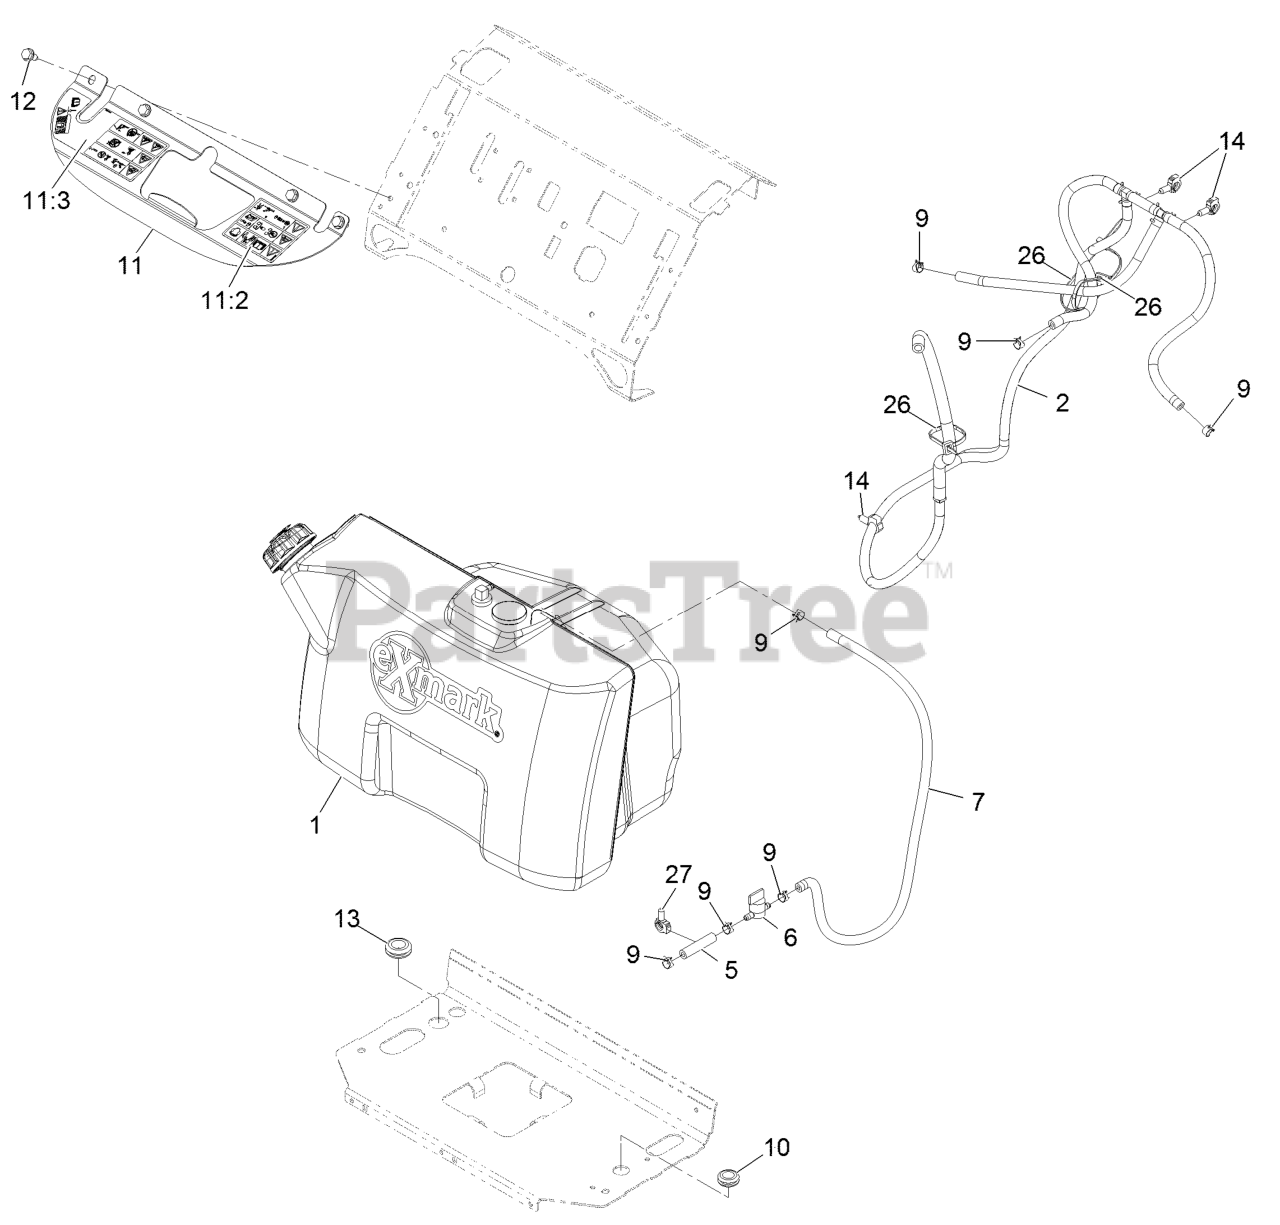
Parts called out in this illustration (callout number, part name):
2	VENT ASM
5	HOSE-FUEL
6	VALVE-FUEL
7	HOSE-FUEL
9	CLAMP-HOSE
10	GROMMET
11	BRACKET-TANK
11:2	DECAL-WARNING LH
11:3	DECAL-WARNING RH
12	Screw-HWH 5/16-18 X 3/4 Tf
13	GROMMET
14	CLIP-HARNESS
26	TIE-CABLE
27	CLIP-HARNESS
